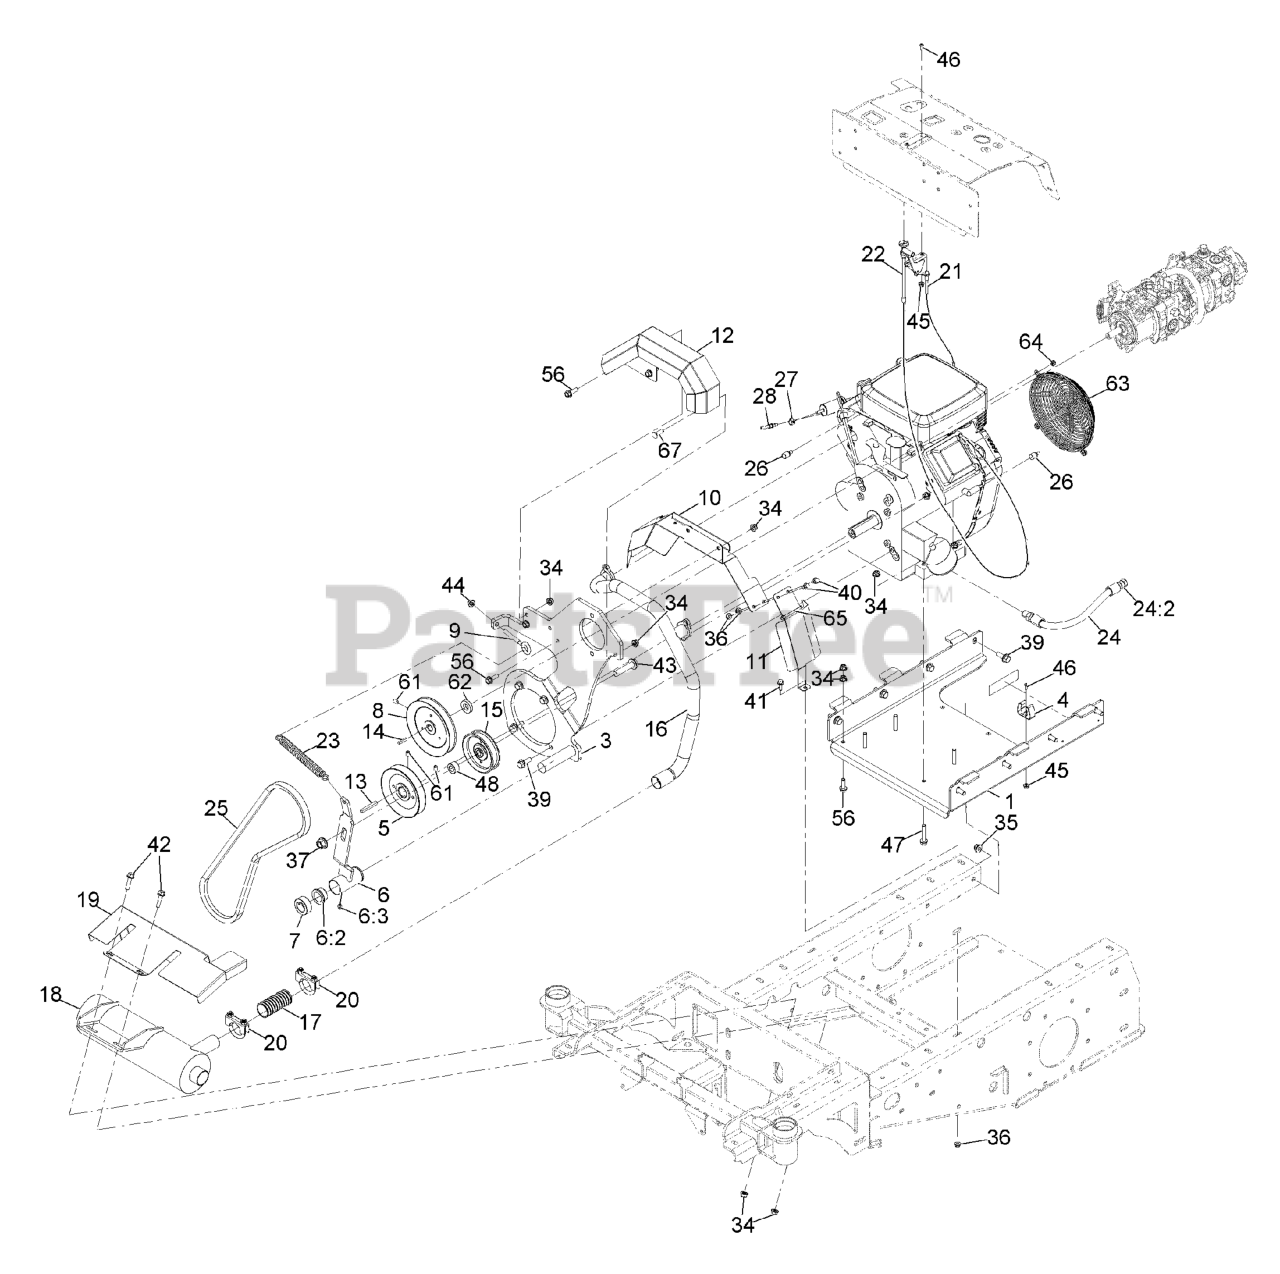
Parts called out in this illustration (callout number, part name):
1	Tray-Engine
3	Bracket-Engine, Pump [black]
4	Holder-Tool, Clip
5	PULLEY-DRIVE
6	Arm-Tension, ASM
6:2	BUSHING-FLANGE
6:3	FITTING-GREASE, ZERK
8	PULLEY-DRIVE, PUMP
9	Bolt-Eye
10	Guard, Lower Muffler
11	Guard, Lower Muffler
12	Guard-Pulley
15	PULLEY-IDLER, FLAT
16	Manifold-Exhaust
17	TUBE-EXHAUST, FLEX
18	MUFFLER
19	SHIELD-HEAT, MUFFLER
20	Clamp-Muffler
21	CABLE-THROTTLE
22	CABLE-CHOKE
23	SPRING-EXTENSION
24	ASM, Oil Drain Hose W/Plug
26	Tube-Heat Shrink, 1/2
27	CLAMP-HOSE
28	BARB-FUEL
34	Nut-Hex Flange
35	Nut-Hex Flange
36	Nut-Hex Flange
37	Nut-Lock 1/2-13
39	SCREW-HHF
40	SCREW-HHF
41	Screw-HHF
42	SCREW-HHF
43	Screw-HHF
44	NUT-HF, NI
45	Nut-Hex Flange
46	Screw-HSBH
47	Screw-HHF
56	SCREW-HHF
61	Setscrew-HSH
63	GUARD-WIRE, VANGUARD
65	TIE-CABLE
67	Bolt,Carriage,5/16-18X1,ST/ST 18-8
